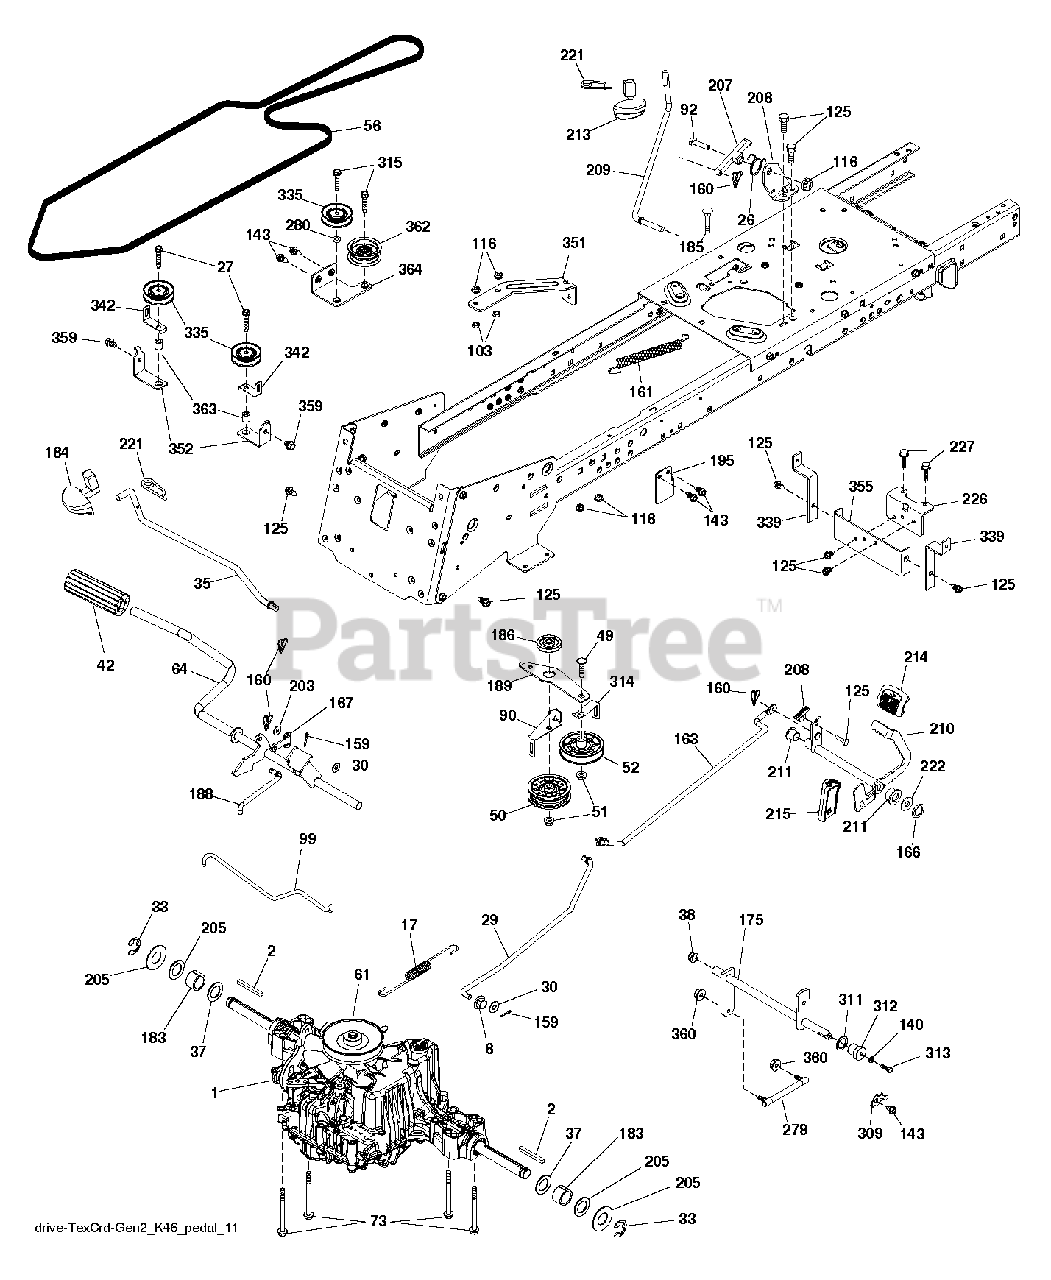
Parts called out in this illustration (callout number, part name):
2	SQUARE KEY
6	GROMMET T
26	SPRING.RETURN.CRUISE
33	E-RING LT
35	ROD.BRAKE.PARTK.HUSQ.TEX
37	WASHER.HARDENED
38	NYLINER SNAP 5/8" ID
42	PEDAL COVER T
49	BOLT
50	IDLER.FLAT.910.OFFSET
51	NUT LOCK FLG 3/8-16 UNC
52	IDLER.V-GROOVE.910.OFFSET
64	SHAFT.ASM.PEDAL.BRK.CNTR
73	BOLT HEX 5/16-18 GR 5
92	BOLT
103	JAM NUT TI
116	NUT LOCK HEX FLANGE 5/16-18
125	SCREW
140	LOCKWASHER
159	COTTER PIN
160	RETAINER CLIP
161	SPRING, RETURN LT
166	NUT.PUSH.625
167	LATCH.BRAKE.SPRING
183	SPACER AXLE
184	HANDLE.PARKG.BRK.HUSQ/PRED.667
186	SPACER.RETAINER
188	LINK.CLUTCH.GROUND.DRIVE
203	WASHER
206	BRKT.MOUNT.LATCH.CRUIS
207	LATCH.CONTROL.CRUISE
208	GEAR.SECTOR.CONTROL.CR
209	ROD.CONTROL.CRUISE.GT.
210	ROCKER.ASM.PEDAL.CONTR
211	BEARING.NYLON
213	KNOB.CONTROL.CRUSIE.HU
214	PAD PEDAL FORWARD
221	RETAINER.SPRING.CLIP.H
222	WASHER 21/32 X 1-1/4 X 10 GA.
226	BRACKET.MOUNT.TORQUE.K46.TLT
227	SCREW
309	PLATE.FASTENING.CROSS.SHAFT
311	WASHER NYL
315	BOLT.5/16-18X1.25
335	PULLEY.V-IDLER.
